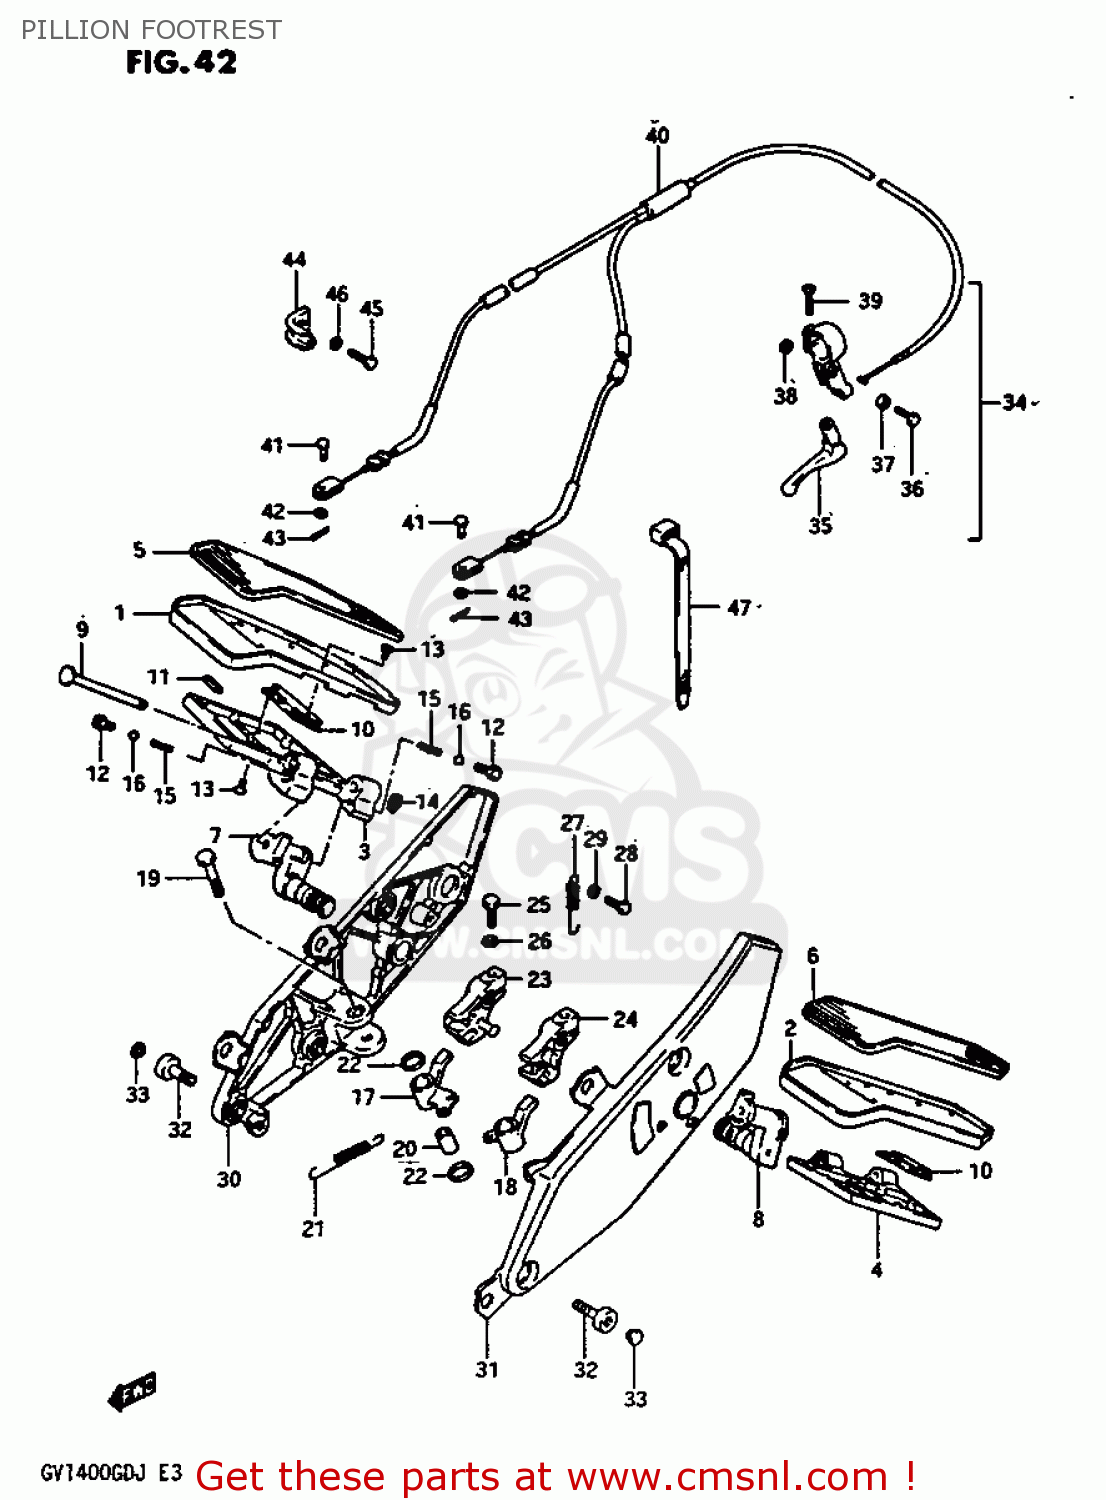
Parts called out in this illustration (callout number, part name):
1	BOARD,PILLION FOOT,UPPER
2	BOARD,PILLION FOOT,UPPER
3	BOARD,PILLION FOOT,LOWER
4	BOARD,PILLION FOOT,LOWER
5	RUBBER,PILLION FOOTBOARD
6	RUBBER,PILLION FOOTBOARD
7	BAR,PILLION FOOTBOARD
8	BAR,PILLION FOOTBOARD
9	PIN,PILLION FOOTREST
10	CUSHION,PILLION BOARD
11	CUSHION,FOOTBOARD
12	BOLT,PILLION BOARD SPRING
13	SCREW(5X10)
14	CIRCLIP,10MM
15	SPRING
16	BALL
17	LEVER COMP,FOOTBOARD
18	LEVER COMP,FOOTBOARD
19	BOLT(10X38)
20	SPACER,PILLION BOARD,LEFT
21	SPRING
22	SHIM
23	CAM,PILLION FOOT BOARD
24	CAM COMP,PILLION FOOT
25	BOLT
26	LOCK WASHER
27	SPRING
28	BOLT
29	NUT 6MM
30	BRACKET
31	BRACKET
32	BOLT 10X30
33	CAP
34	LEVER ASSEMBLY,PILLION FOOT
35	LEVER
36	BOLT
37	SPACER,DECOMPRESSION LEVER
38	NUT 8MM
39	SCREW
40	CABLE,PILLION FOOT REST
41	PIN(L:13)
42	WASHER
43	PIN
44	BRACKET, FOOTREST
45	BOLT
46	WASHER,LOCK
47	CLAMP(L:165)
